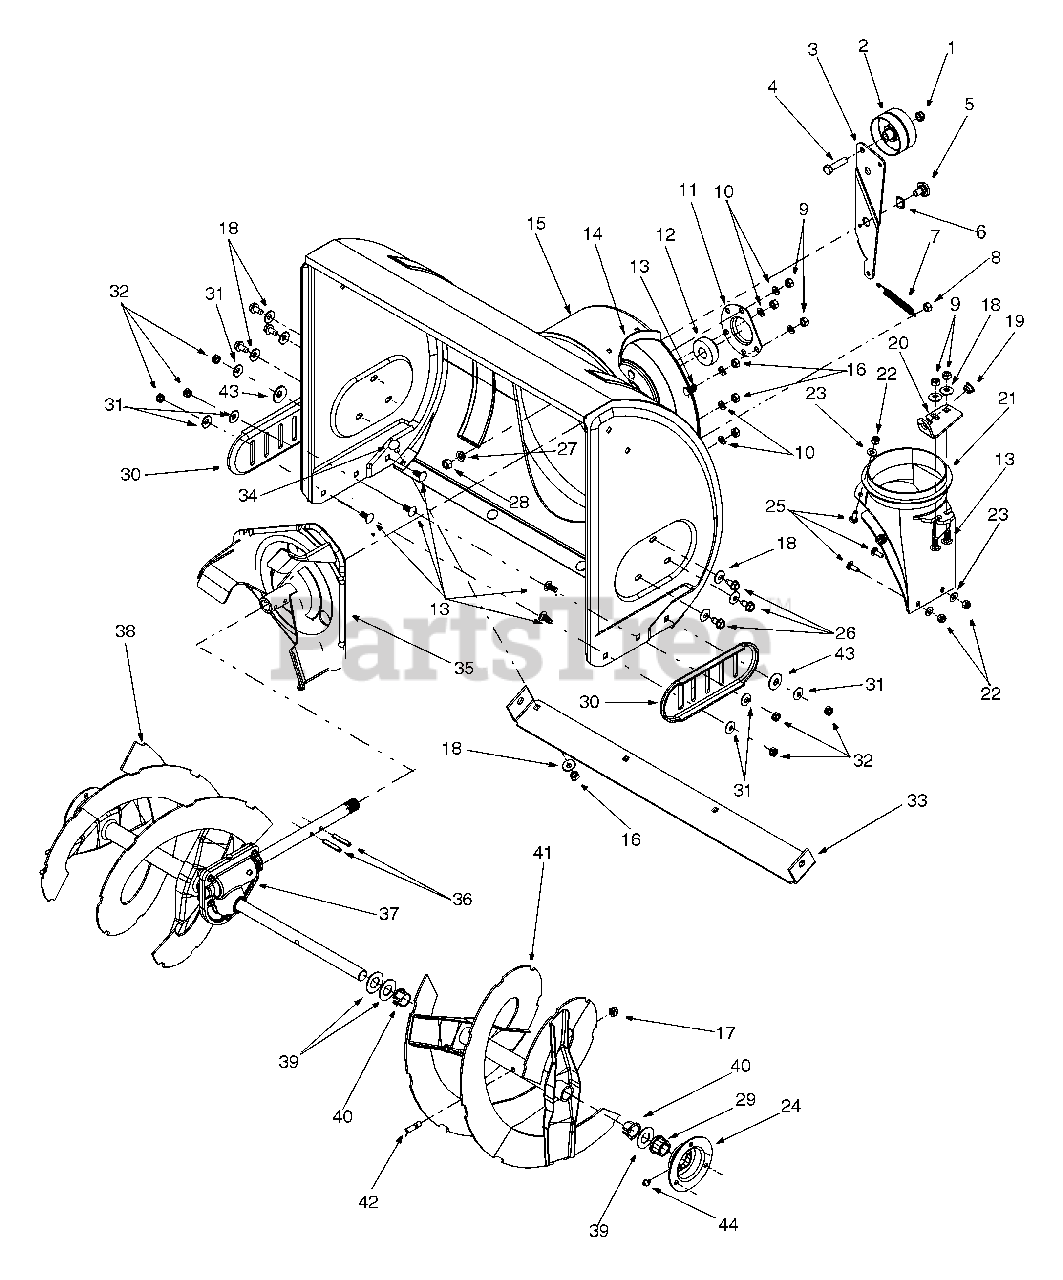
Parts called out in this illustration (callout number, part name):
1	Lock Jam Nut 3/8-24
2	Flat Idler, 2.75 w/o Flanges
4	Hex Cap Screw 3/8-24 x 1.50
5	Shoulder Screw
6	Wave Washer
7	Extension Spring
8	Hex Nut 5/16-18
9	Hex Lock Nut 5/16-18
10	Lock Washer 5/16
11	Bearing Housing, 1.85
12	Ball Bearing, .75 x 1.85
13	Carriage Bolt 5/16-18 x .75
17	Lock Nut 5/16-18
18	Bell Washer
19	Plastic Bushing, .380
21	Chute Adapter, 5.0
22	Hex Lock Nut 1/4-20
23	Flat Washer
24	Bearing Housing w/ Fitting Hole
25	Carriage Screw 1/4-20 x .75
26	Hex Washer Screw 5/16-18
27	Lock Washer 3/8
28	Hex Nut 3/8-16
29	Hex Flange Bearing
31	Bell Washer
32	Hex Nut 5/16-18
34	Carriage Bolt 5/16-18 x .62
36	Spiral Pin, .25 x 1.5
37	24" Gearbox Ass'y w/ Fitting
40	Flange Bushing
42	Shear Bolt 5/16-18 x 1.5
43	Flat Washer, .344 x 1.12 x .87
44	Grease Fitting, 3/16" Drive
